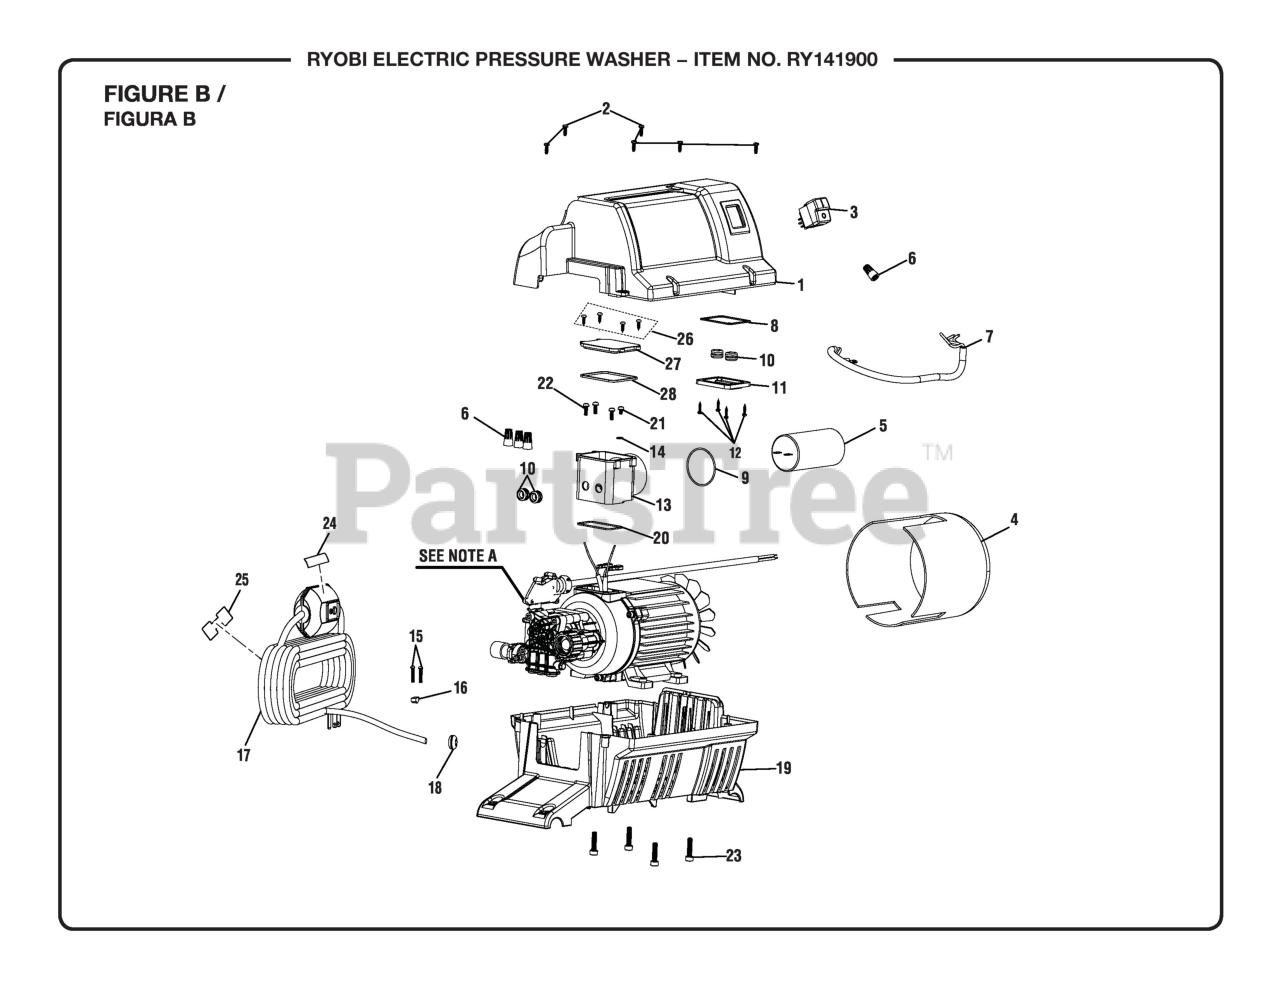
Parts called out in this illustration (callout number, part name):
1	Top Motor Housing
2	Screw (M4.2 x 15 mm, Phillips Hd. S.T.)
3	On/Off Switch
4	Nozzle (15deg)
5	Capacitor
6	Tuerca para alambre
7	Connecting Wire
8	Gasket (Switch Cover)
9	O-ring (Capacitor)
10	Soap Tank Grommet
11	Switch Cover
12	Screw (M2.9 x 14 mm, Pan Hd.)
14	Toothed Lock Washer (M4)
15	Screw (M3.5 x 20 mm, Button Hd.)
16	Cord Clamp
17	Power Cord
18	Housing Rubber Grommet
19	Lower Motor Housing
20	Wire Box Gasket (Lower)
21	Screw (M4 x 16 mm, Pan Hd.)
22	Bolt (M4 x 12 mm, Pan Hd.)
23	Bolt (M6 x 20 mm, Hex Hd. Locking)
24	Power Cord Label
25	Cordwrap Warning Label
26	Screw (ST 3.5)
27	Wire Box Cover
28	Wire Box Gasket (Upper)
